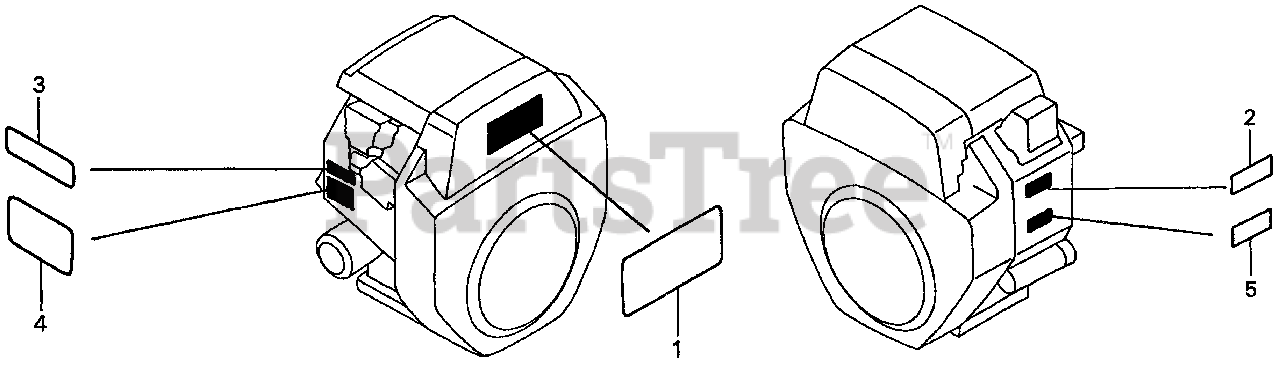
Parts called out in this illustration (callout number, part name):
1	MARK, EMBLEM (GX620)
3	LABEL, SPECIFICATION (GX620)
4	LABEL, CAUTION
5	MARK, OIL ALERT (E)
